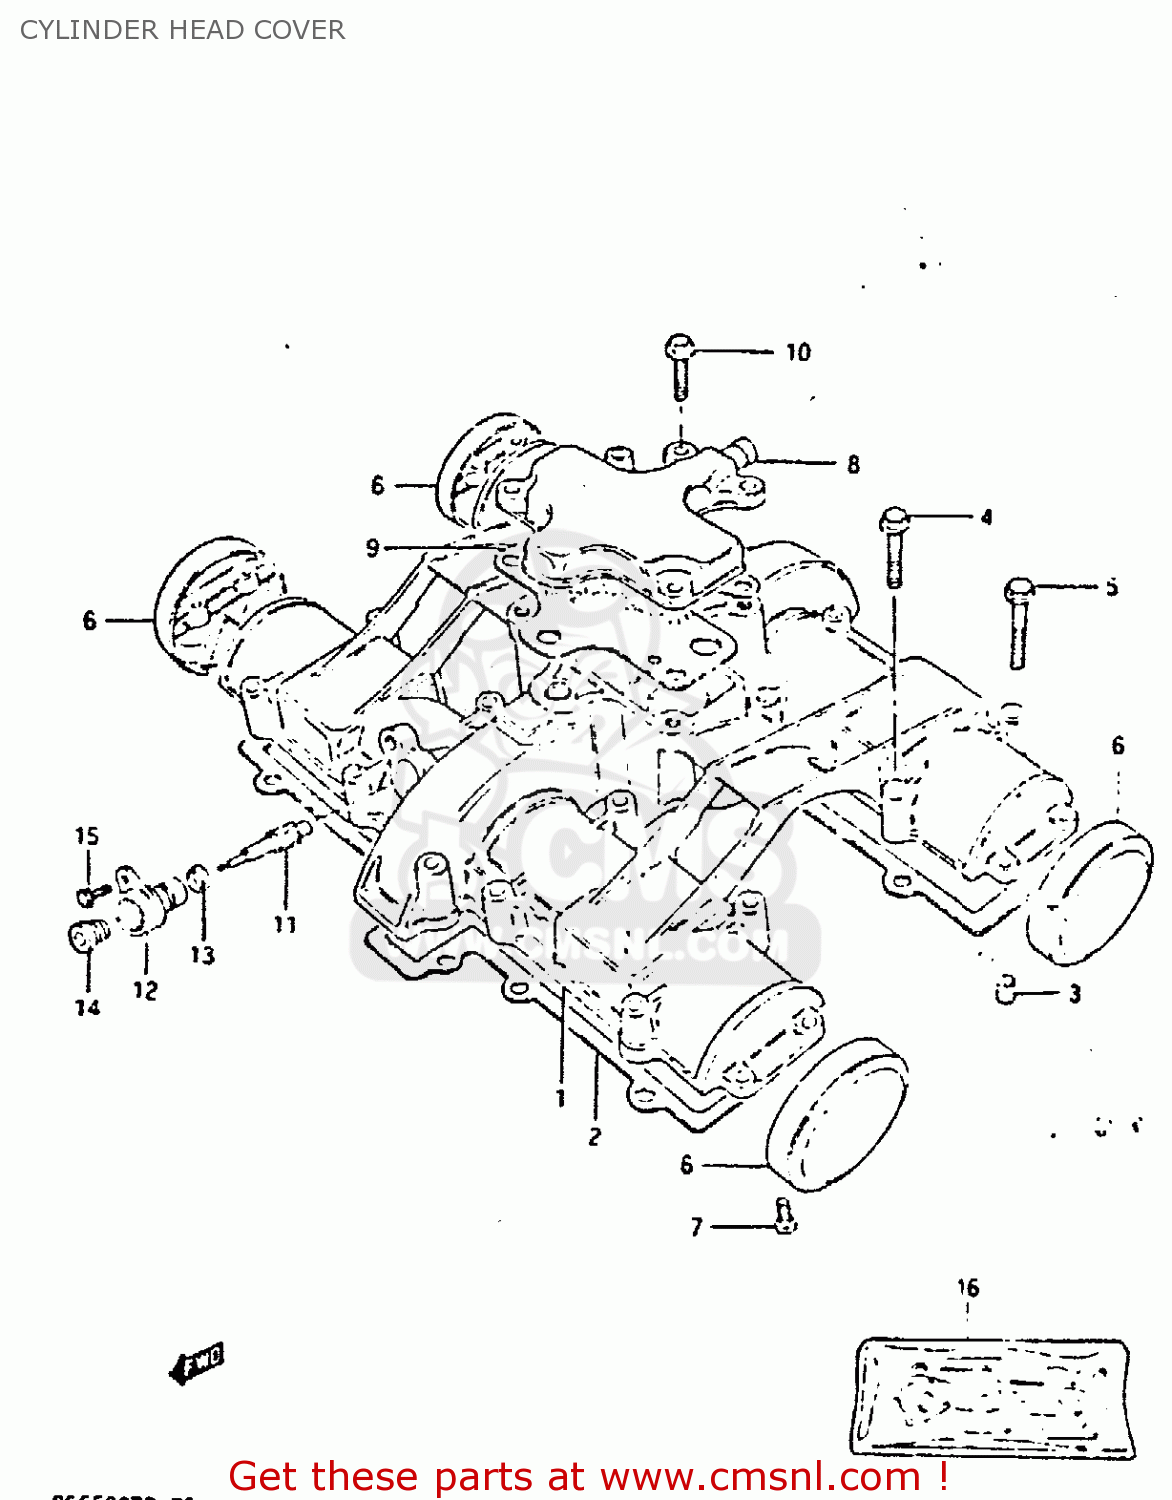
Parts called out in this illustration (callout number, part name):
1	COVER,CYLINDER HEAD
2	GASKET,CYLINDER HEAD COVER (MCA)
3	PIN(6.2X8X11)
4	BOLT (6X40)
5	BOLT (6X45)
6	CAP,CYLINDER HEAD COVER
7	SCREW
8	COVER,BREATHER
9	GASKET (MCA)
10	BOLT
11	GEAR,TACHOMETER DRIVEN
12	SLEEVE,TACHOMETER DRIVE GEAR
13	SEAL,TACHOMETER DRIVEN
14	SEAL,OIL(5X12X8)
15	SCREW(5X12)
16	GASKET SET
